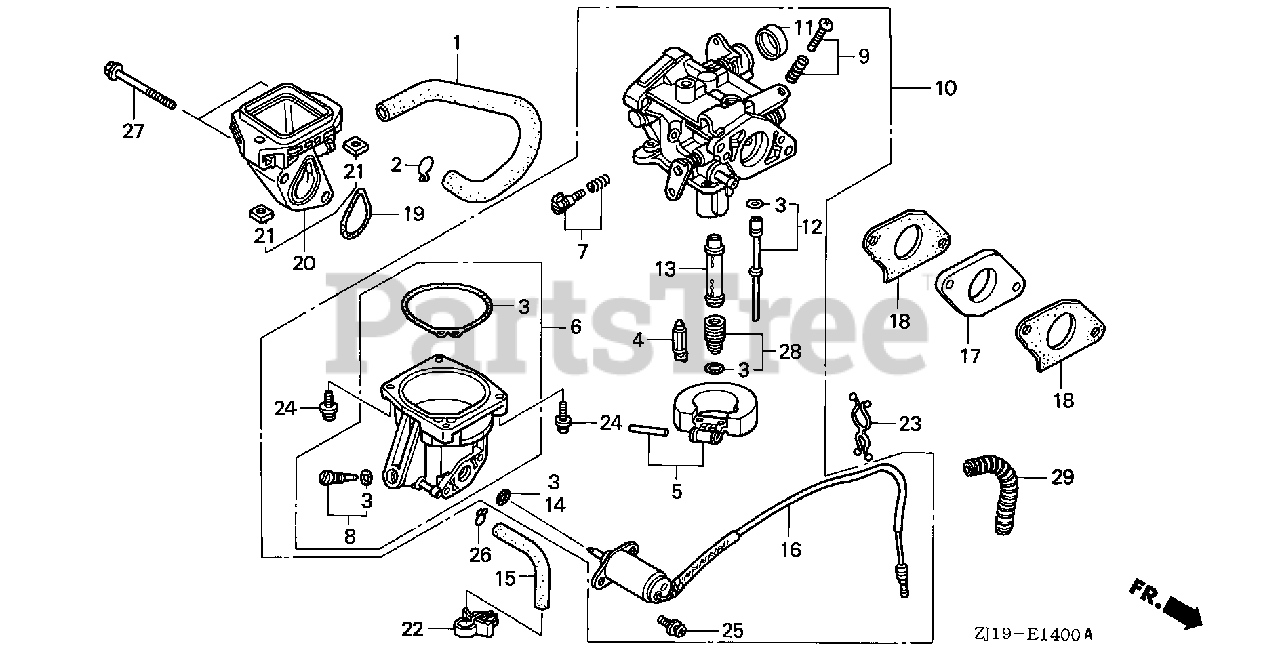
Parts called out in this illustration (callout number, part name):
1	TUBE, BREATHER
2	CLIP, BREATHER TUBE
3	GASKET SET
4	VALVE SET, FLOAT
5	FLOAT SET
6	CHAMBER SET, FLOAT
7	SCREW SET
8	SCREW SET, DRAIN
9	SCREW SET
10	CARBURETOR ASSY. (BG22J A)
11	CAP, CHOKE LEVER DUST
12	JET SET (#52)
13	NOZZLE, MAIN
14	O-RING (5.8X1.9)
15	TUBE, DRAIN
16	VALVE ASSY., SOLENOID
17	INSULATOR, CARBURETOR
18	GASKET, CARBURETOR
19	GASKET, AIR CLEANER
20	ELBOW COMP., AIR CLEANER
21	NUT, INSERT (6MM)
22	CLIP B, CABLE
23	CLIP, PURSE LOCK
24	SCREW-WASHER (4X14)
25	SCREW-WASHER (5X12)
26	CLIP, TUBE (B8)
27	BOLT, FLANGE (6X120)
28	JET SET, MAIN (#100)
28	JET SET, MAIN (#102)
28	JET SET, MAIN (#105)
29	TUBE, CORRUGATE
